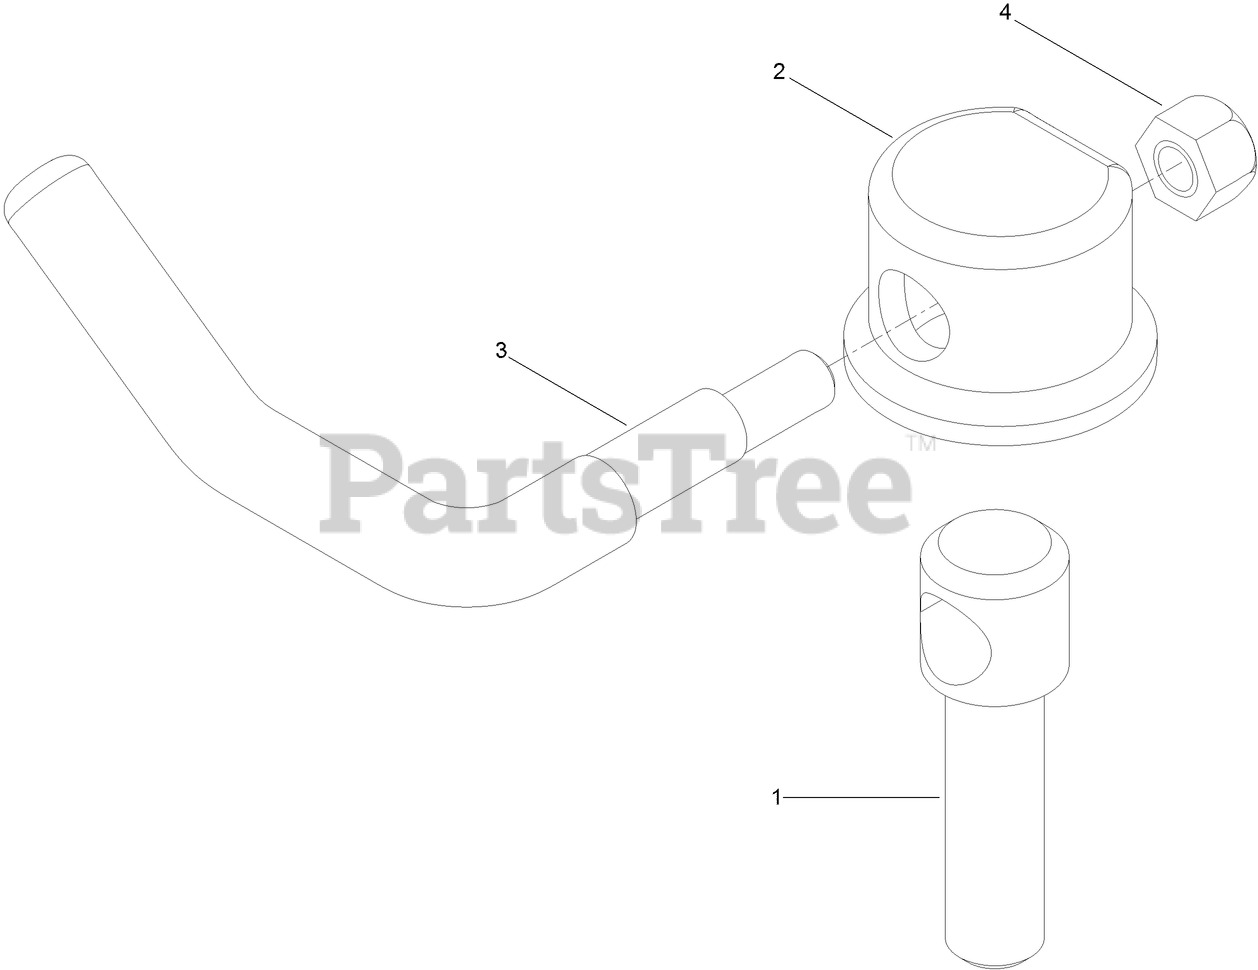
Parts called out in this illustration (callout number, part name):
1	Screw-Lock
2	CAP-LOCK
3	Lever-Lock
4	NUT-LOCK, NI
